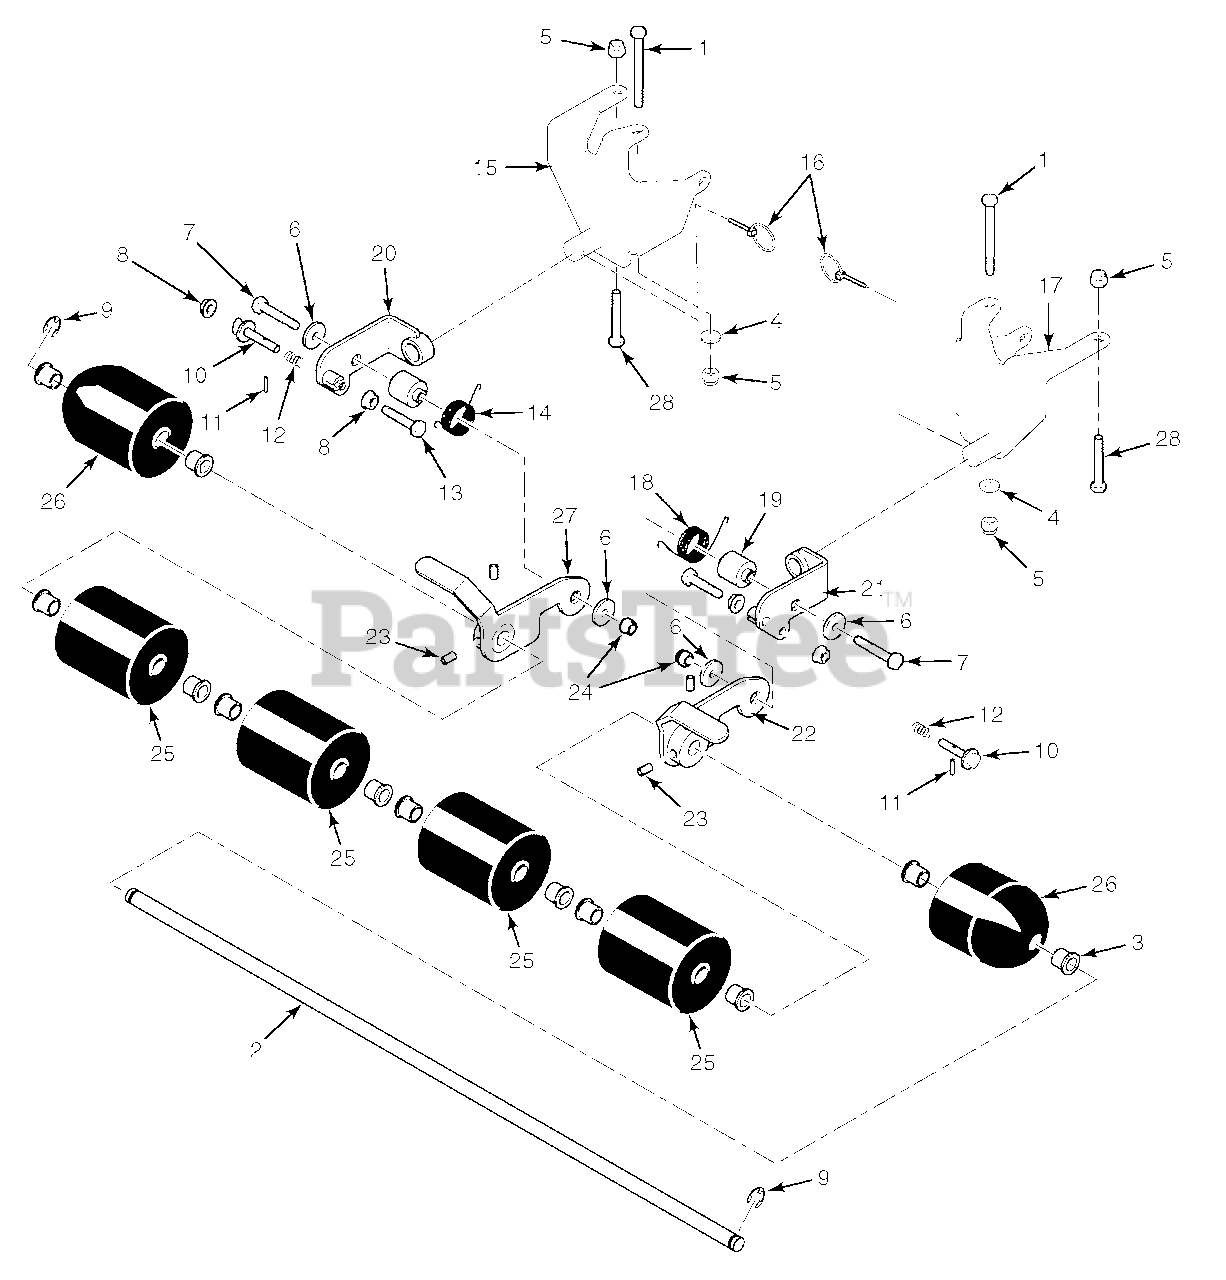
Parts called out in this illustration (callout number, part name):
1	Bolt, Hex Head 5/16-18 x 4-1/2"
2	Roller Shaft
3	Bushing, .752 Oilite
4	Flatwasher, 5/16-.378 x .875 x .083
5	Nut, Elastic Stop 5/16-18
6	Flatwasher, 3/8-.406 x 1-1/2" 7 Gauge
7	Bolt, Hex Head 3/8-16 x 2-3/4"
8	Nut, Serrated Flange 3/8-16
9	Retaining Ring, .750 External "E"
10	Pin, Lift Latch
11	Pin, Slotted Spring 5/32" x 7/8"
12	Spring, Lock Pin
13	Bolt, Hex Head 3/8-16 x 2-1/2"
14	Spring, Torsion LH
15	Mounting Bracket Weldment, LH
16	Quick Pin, .188 Dia.
17	Mounting Bracket Weldment, RH
18	Spring, Torsion RH
19	Hub, Striper
20	Pivot Weldment, LH
21	Pivot Weldment, RH
22	Hinge Weldment, RH
23	Set Screw, 3/8-16 x 1/2"
24	Nut, Elastic Stop 3/8-16
25	Roller Assembly
26	Roller Assembly, Striper End
27	Hinge Weldment, LH
28	Bolt, Hex Head 5/16-18 x 3-1/4"
